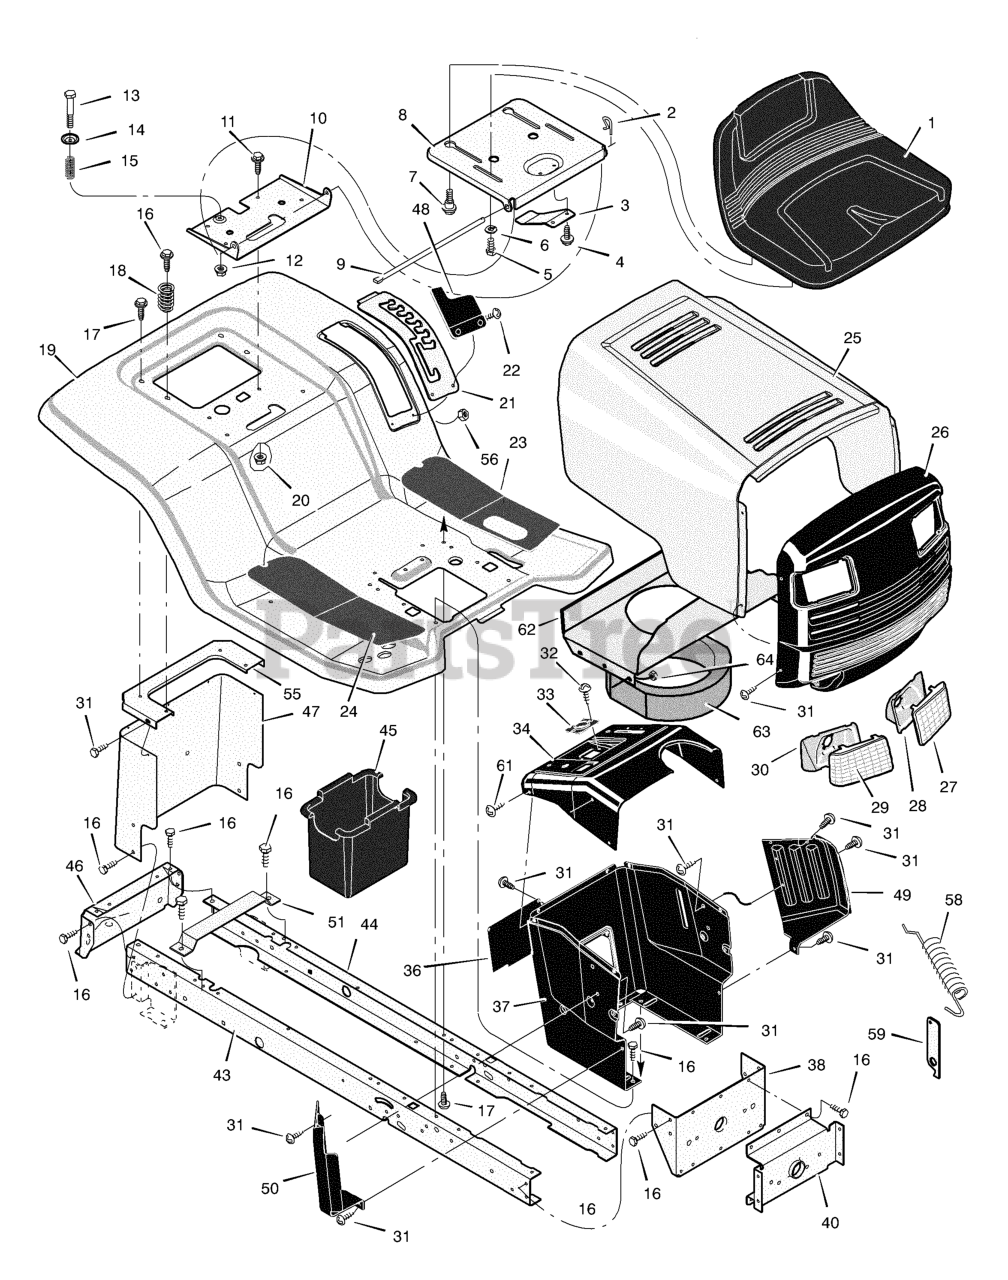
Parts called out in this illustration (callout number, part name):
1	Seat
2	Cap, Push On
5	Bolt, Wing
6	Washer
7	Bolt, Shoulder
8	Support, Seat
9	Rod, Pivot
10	Bracket, Pivot
11	Bolt
13	Bolt, Shoulder
15	Spring
19	Deck, Seat
20	Nut
21	Plate, Index
23	Mat, Left
24	Mat, Right
27	Lens, Left
28	Bezel, Left
29	Lens, Right
30	Bezel, Right
31	Screw
33	Bearing, Steering
36	Panel, Access
37	Support, Dash
38	Bracket, Rear Hanger
40	Axle, Hanger
42	Bolt, Shoulder
43	Frame, Right
44	Frame, Left
45	Container, Battery
46	Plate, Hitch
47	Plate, Rear
48	Cover, Detent
49	Panel, Left Side
50	Panel, Right Side
51	Support Battery
55	Plate, Rear
56	Locknut
58	Extension, Spring
59	Bracket
63	Foam (4 Required)
64	Nut, Keps
70	Holder, Beverage
